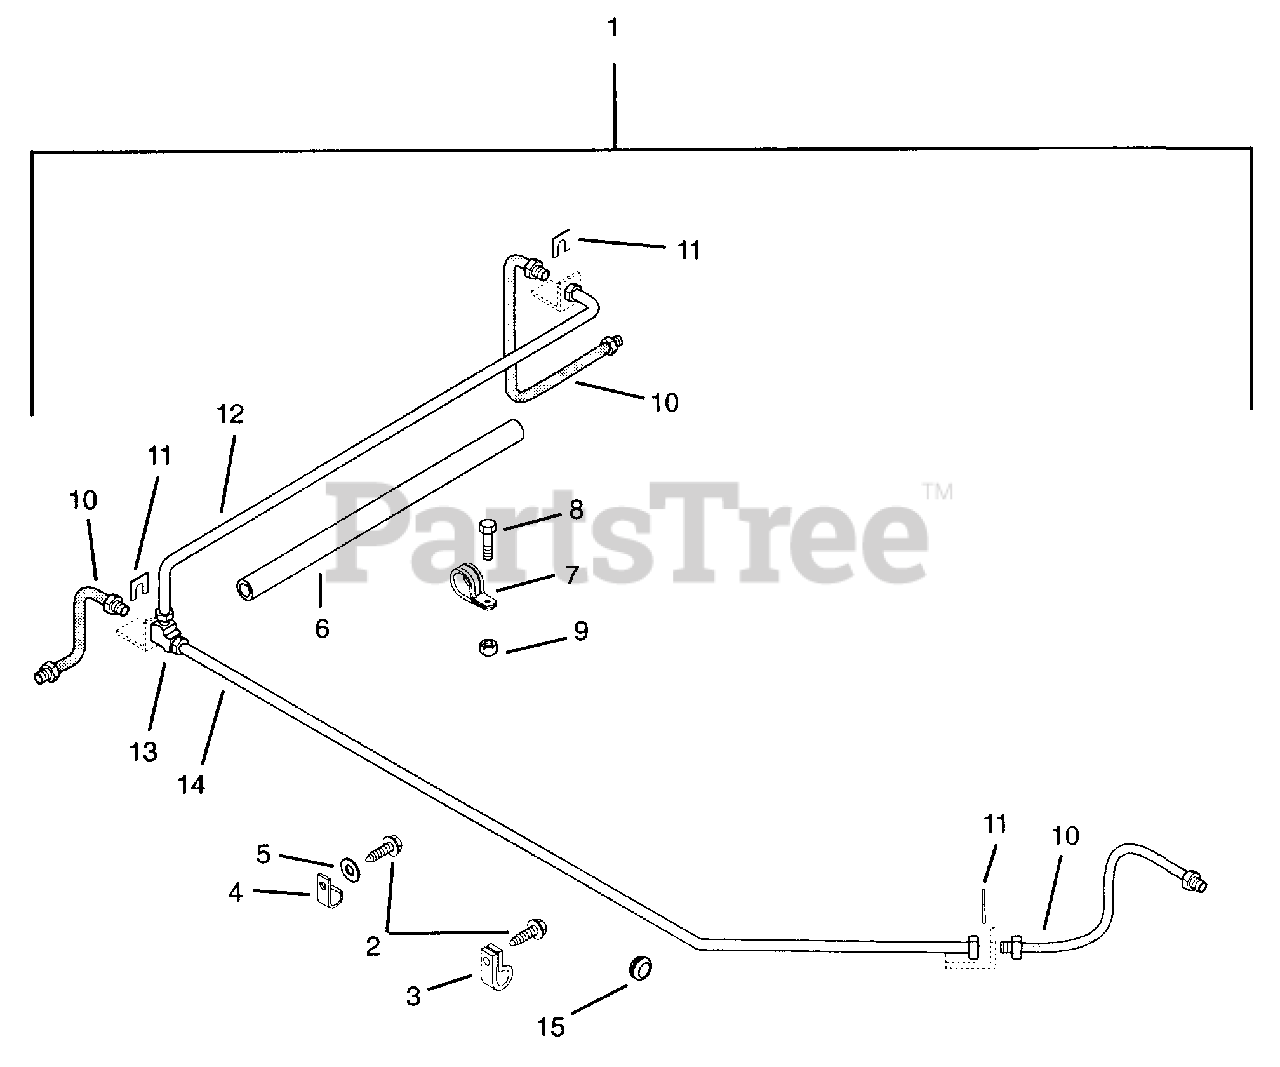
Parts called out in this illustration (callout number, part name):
1	Brake Line Kit
2	Screw-Tapping-Hex Washer Head .25 x .50
5	Washer-Flat-Steel .38 x .875 x .083
6	Tube-Brake Line Protective
7	Clamp-Steel 1.0
8	Bolt-Hex .38-16 x 1.00 Grade 5
9	Nut-Locking-Center .38-16
10	Hose-18" Hydraulic Brake
11	Clip-Hose
12	Line-Brake 3/16 x 72
13	Tee-3/16 Adapter
14	Line-Brake 3/16 x 100
